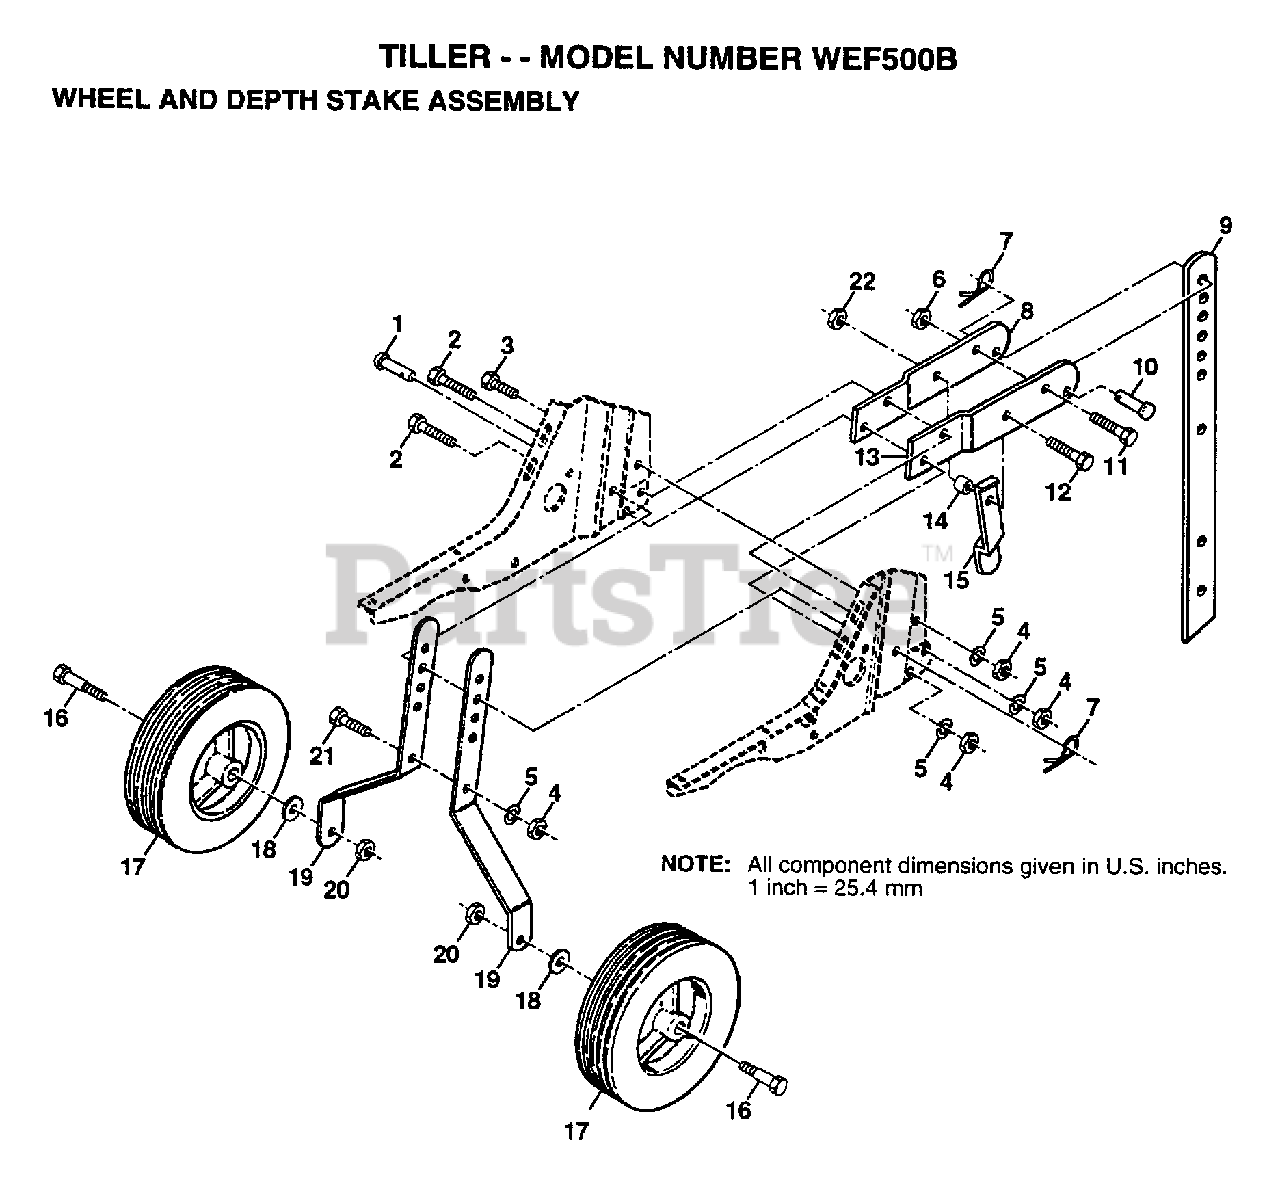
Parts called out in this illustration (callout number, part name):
1	DRILLED RIVET RT
3	BOLT
4	NUT.HEX.5/16-18
5	LOCKWASHER
6	NUT
7	SPRING.RETAINER
8	SUPPORT STAKE RH
11	BOLT
12	BOLT.HEX.5/16-1.5
13	SUPPORT STAKE LH
14	WASHER
15	STAKE SPRING TI
16	BOLT SHOULDER
17	WHEEL.8X1.75.YELL
18	WASHER
19	BRACKET.WHL.PNT.
22	NUT
